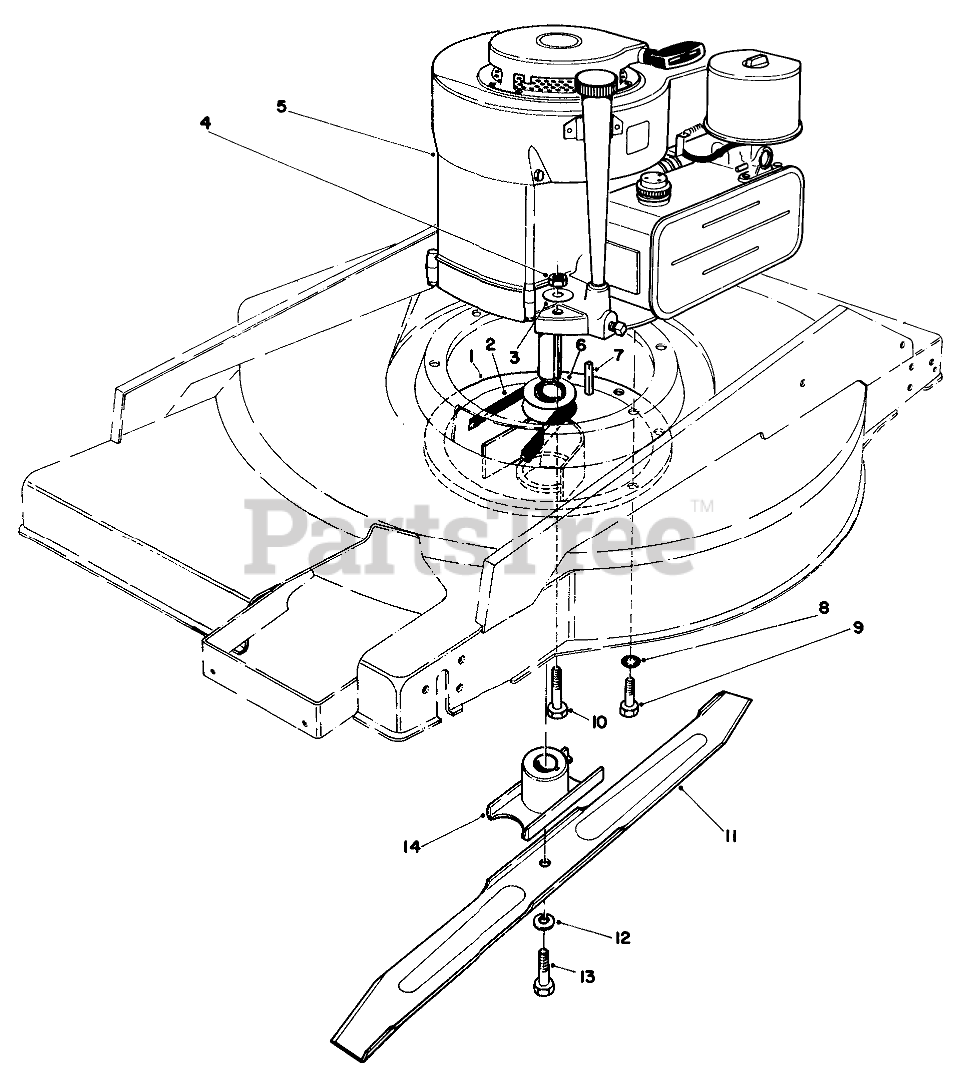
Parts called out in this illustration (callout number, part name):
1	Crankshaft Protector Assy.
2	V-Belt
3	WASHER-FLAT
4	NUT-LOCK, CONE
5	Engine
6	PULLEY DRIVER
7	KEY-SQUARE
8	WASHER-LOCK, INTERNAL
9	SCREW-HWHTF
10	SCREW-HH
11	Blade
12	WASHER-LOCK
13	SPECIAL SCREW
14	BLADE RETAINER W A
